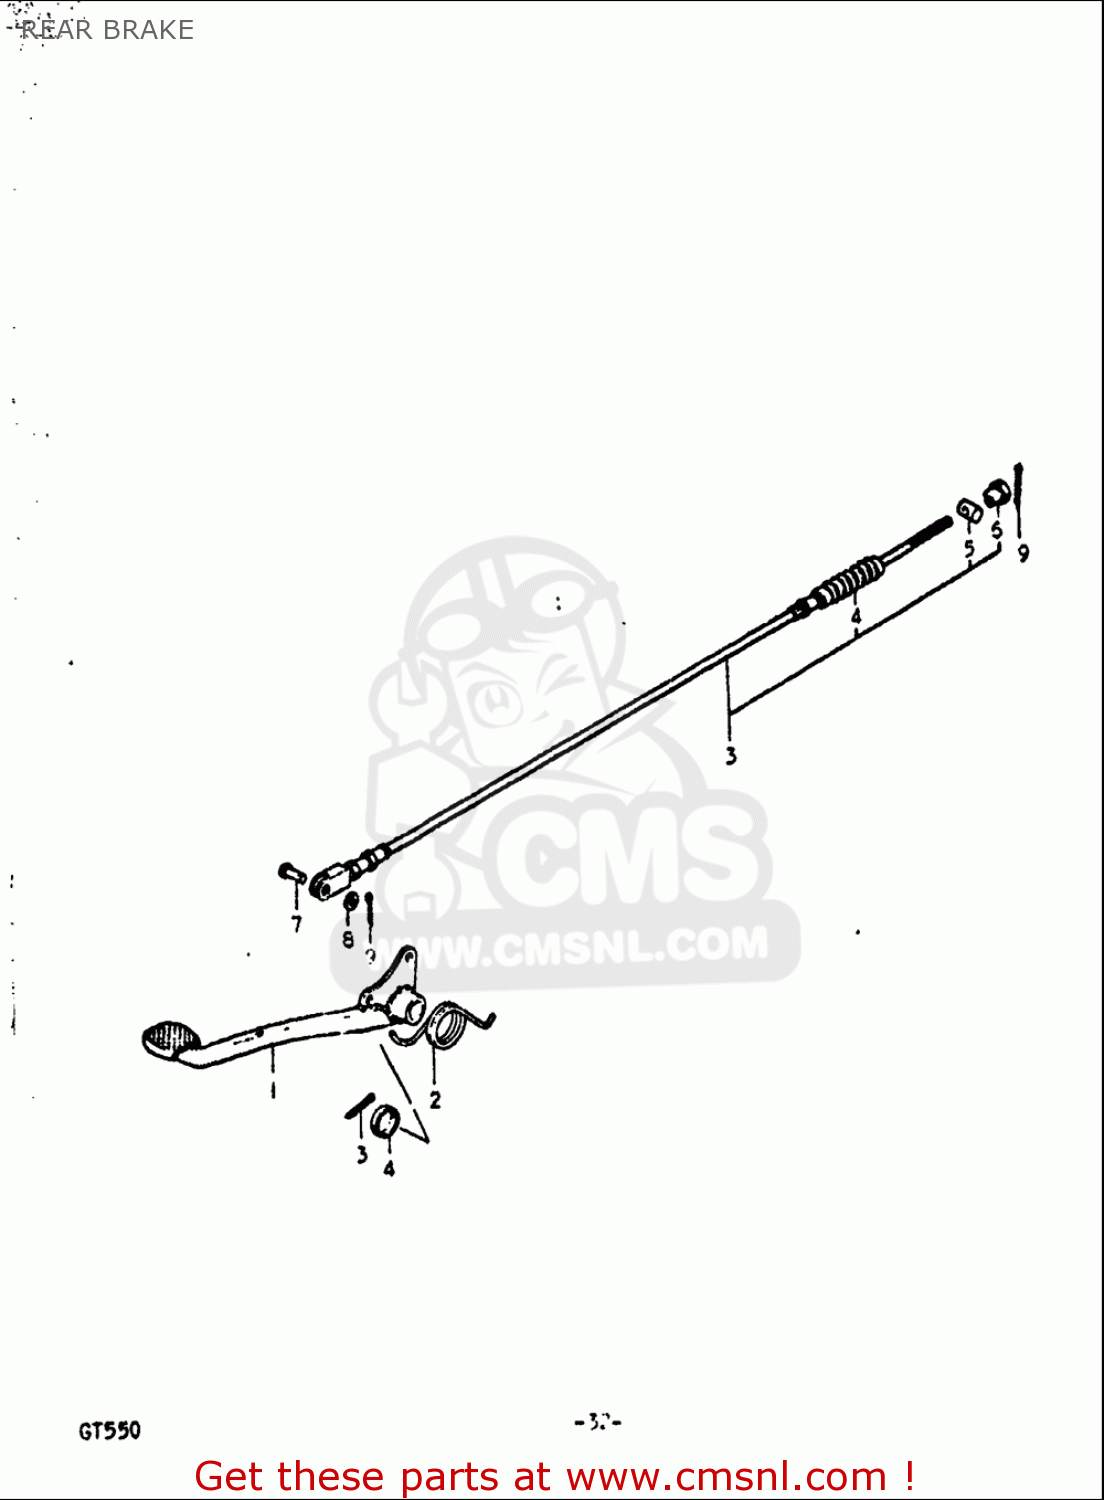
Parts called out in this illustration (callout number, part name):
2	SPRING
4	SEAL,DUST
5	PIN(13X18)
6	NUT
7	PIN(L:17.5)
8	WASHER
9	PIN
